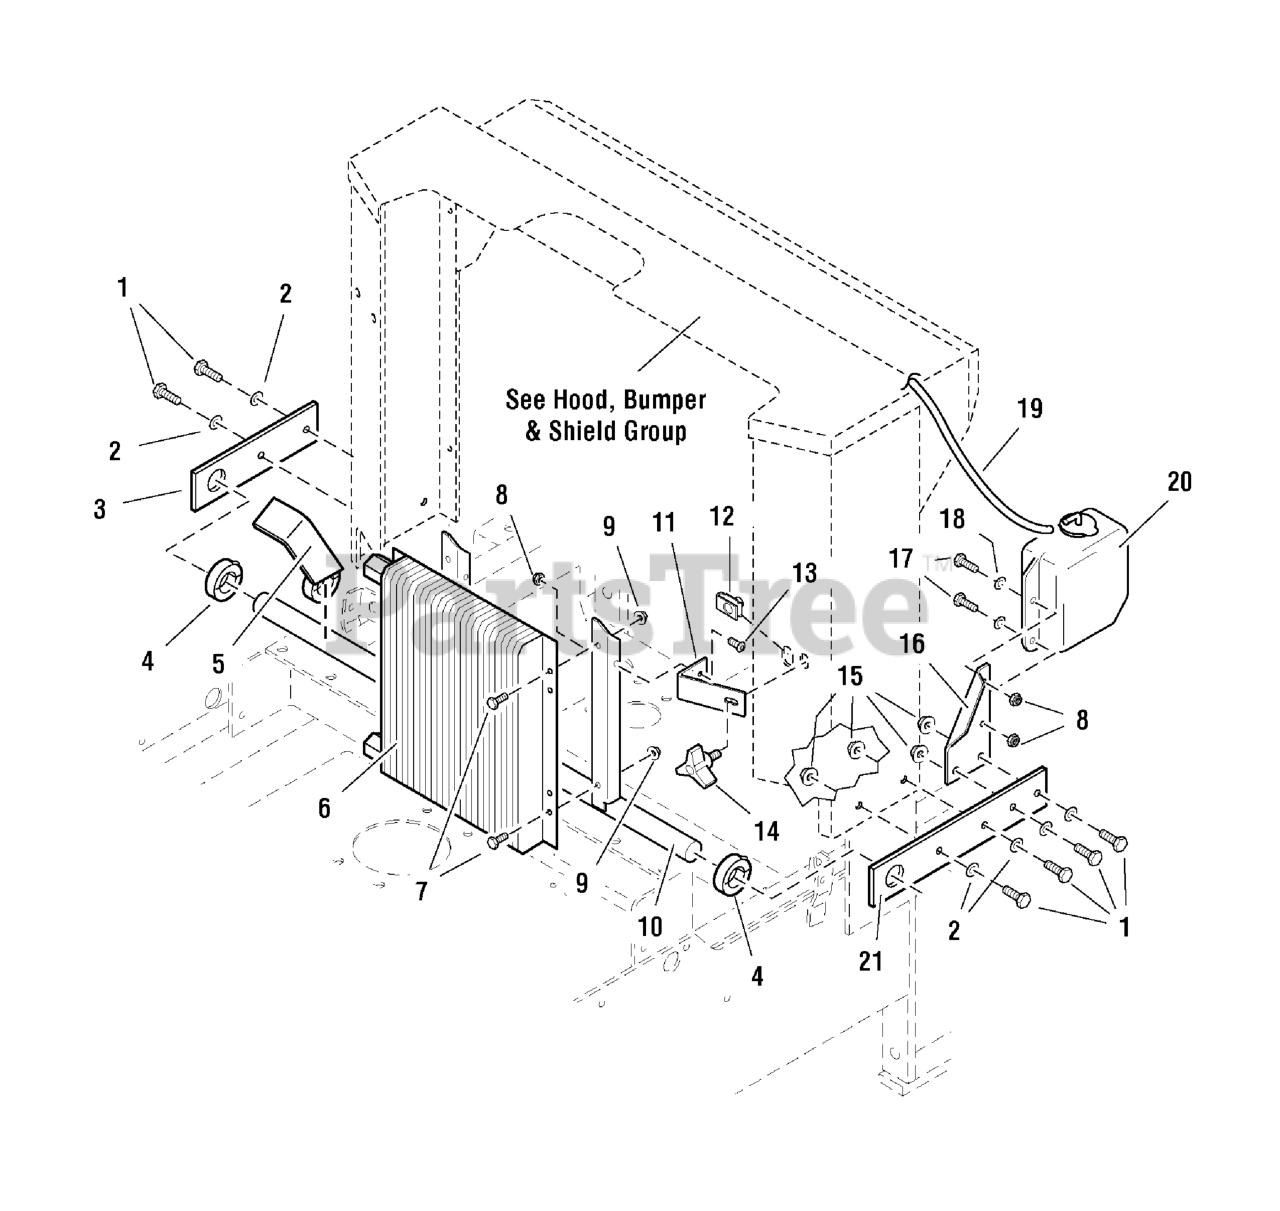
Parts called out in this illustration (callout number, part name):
1	BOLT, 5/16-18 X 1 GD5 YZ
2	WASHER, 3/8 SAE
3	OIL COOLER PIVOT PLATE
4	COLLAR, 1" Split
5	SEAT MOUNT STOP
6	OIL COOLER
7	BOLT, 1/4-20 x 1/2
8	NUT, 1/4-20 HEX NYLON LOCK
9	NUT, 1/4-20 HEX SERR. FLANGE
10	OIL COOLER MOUNT
11	COOLER MOUNT ANCHOR
12	BODY CLIP, 5/16-18-7GA MATERIAL
14	KNOB
15	NUT, 5/16-18 HEX SERRATED FLANGE (LARGE)
16	TANK MOUNT BRACKET
17	BOLT, 1/4-20 X 1" GD5 CZ
18	WASHER, 1/4 SAE
19	HOSE, 36"
20	EXPANSION TANK, Complete
21	OIL COOLER MOUNT PLATE-LH
